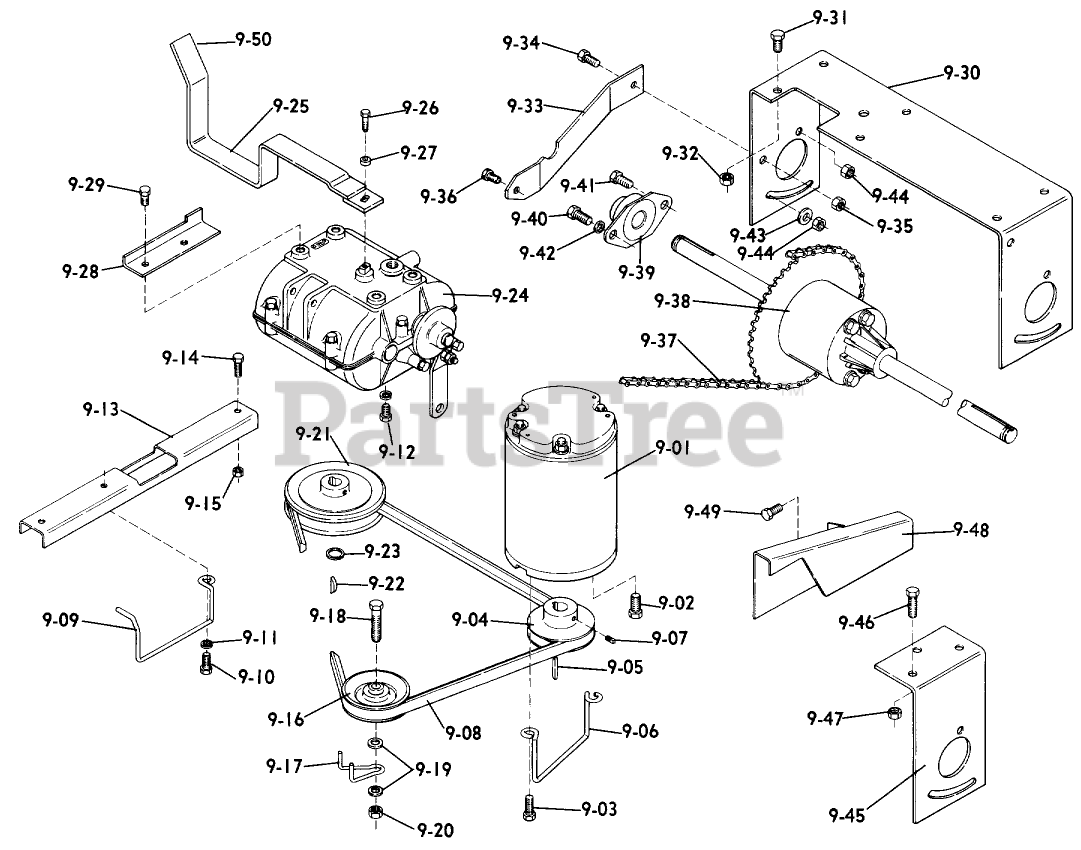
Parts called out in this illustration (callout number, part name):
9-01	Motor-Traction
9-02	Bolt
9-03	Bolt
9-04	Pulley
9-05	KEY-STRAIGHT
9-06	Belt Guide
9-07	Set Screw
9-08	Drive Belt
9-09	Belt Guide
9-10	HHCS
9-11	Lockwasher
9-12	H H C S
9-13	Transmission Brace
9-14	Bolt
9-15	Nut
9-16	PULLEY-IDLER STATION
9-17	BELT GUIDE
9-18	Bolt
9-19	Washer
9-20	Nut
9-21	Pulley, 4" O.D.
9-22	Key
9-23	SNAP RING- 5/8 EXT
9-24	Transmission Assembly (Peerless-706)
9-25	Shift Lever Assembly
9-26	Bolt, 1/4-28 x 3/4
9-27	WASHER
9-28	Stop Reverse
9-29	SCREW
9-30	Axle Bracket
9-31	Bolt
9-32	NUT
9-33	Brace
9-34	Bolt
9-35	NUT
9-36	Bolt, 1/4-20 x 3/4 Swage Form
9-37	Chain
9-38	Differential Assembly (Peerless-167)
9-39	Bearing
9-40	BOLT
9-41	Bolt
9-42	Collar
9-43	WASHER
9-44	NUT
9-45	Axle Bracket
9-46	Bolt
9-47	NUT
9-48	Chain Shield
9-49	SCREW
